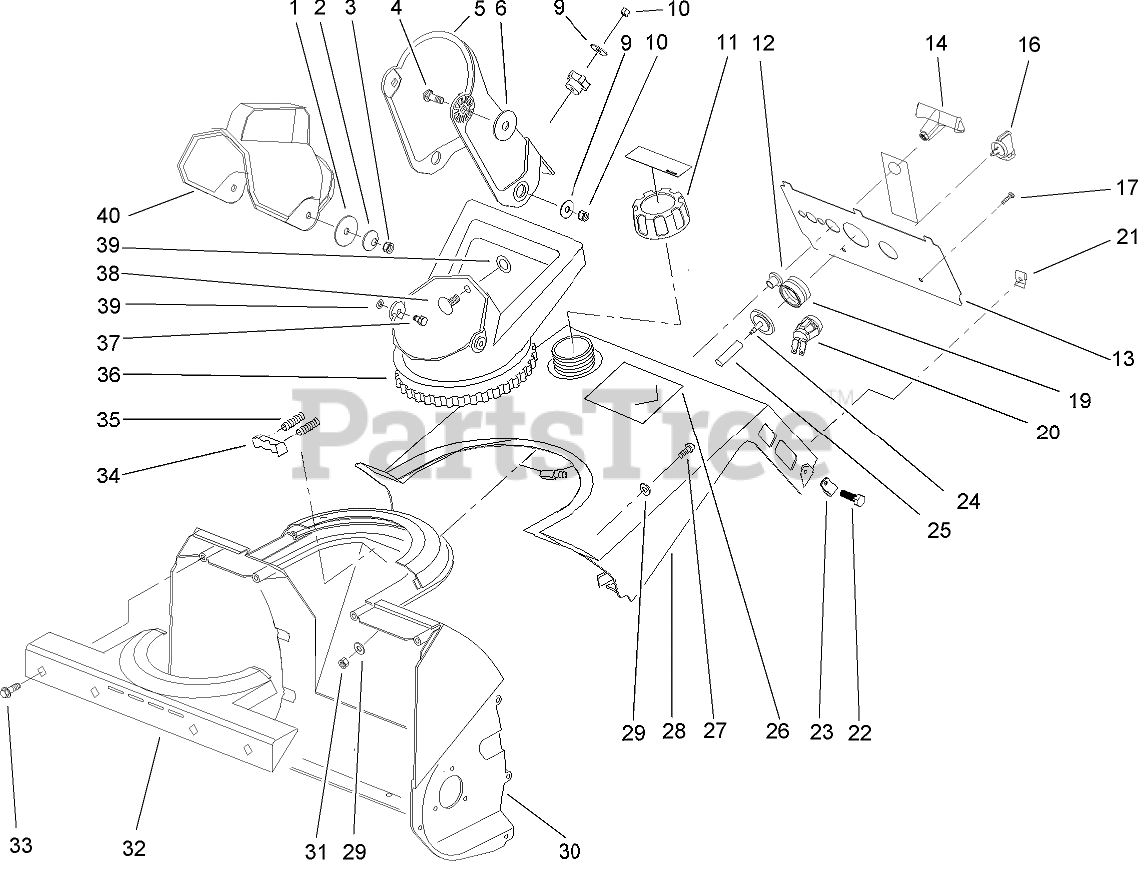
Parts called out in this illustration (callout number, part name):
1	WASHER-FLAT
2	WASHER-BELLEVILLE
3	NUT-LOCK, NI
4	BOLT-CARR
5	CHUTE
6	WASHER-RUBBER
9	WASHER-FLAT
10	NUT-LOCK, NI
11	GAS CAP ASM
12	GUIDE-ROPE, STARTER
13	PANEL-CONTROL
14	HANDLE-STARTER
16	KEY-IGNITION
17	SCREW-SHWH, THREAD FORMING
19	BULB-PRIMER
20	SWITCH
22	SCREW-THREAD FORMING
23	CLAMP
24	BODY-PRIMER
25	HOSE-PRIMER
26	DECAL-POWERLITE
27	SCREW-PPH
28	SHROUD-TANK, GAS UPPER
29	WASHER-FLAT
30	HOUSING
31	NUT-LOCK, NI
32	RETAINER-CHUTE
33	SCREW-PLASTIC
34	DETENT-CHUTE
35	SPRING-COMPRESSION
36	HANDLE-CHUTE
37	SCREW-HH
38	SCREW-CARR
39	PUSHNUT-RETAINER, BOLT
40	DEFLECTOR-CHUTE
